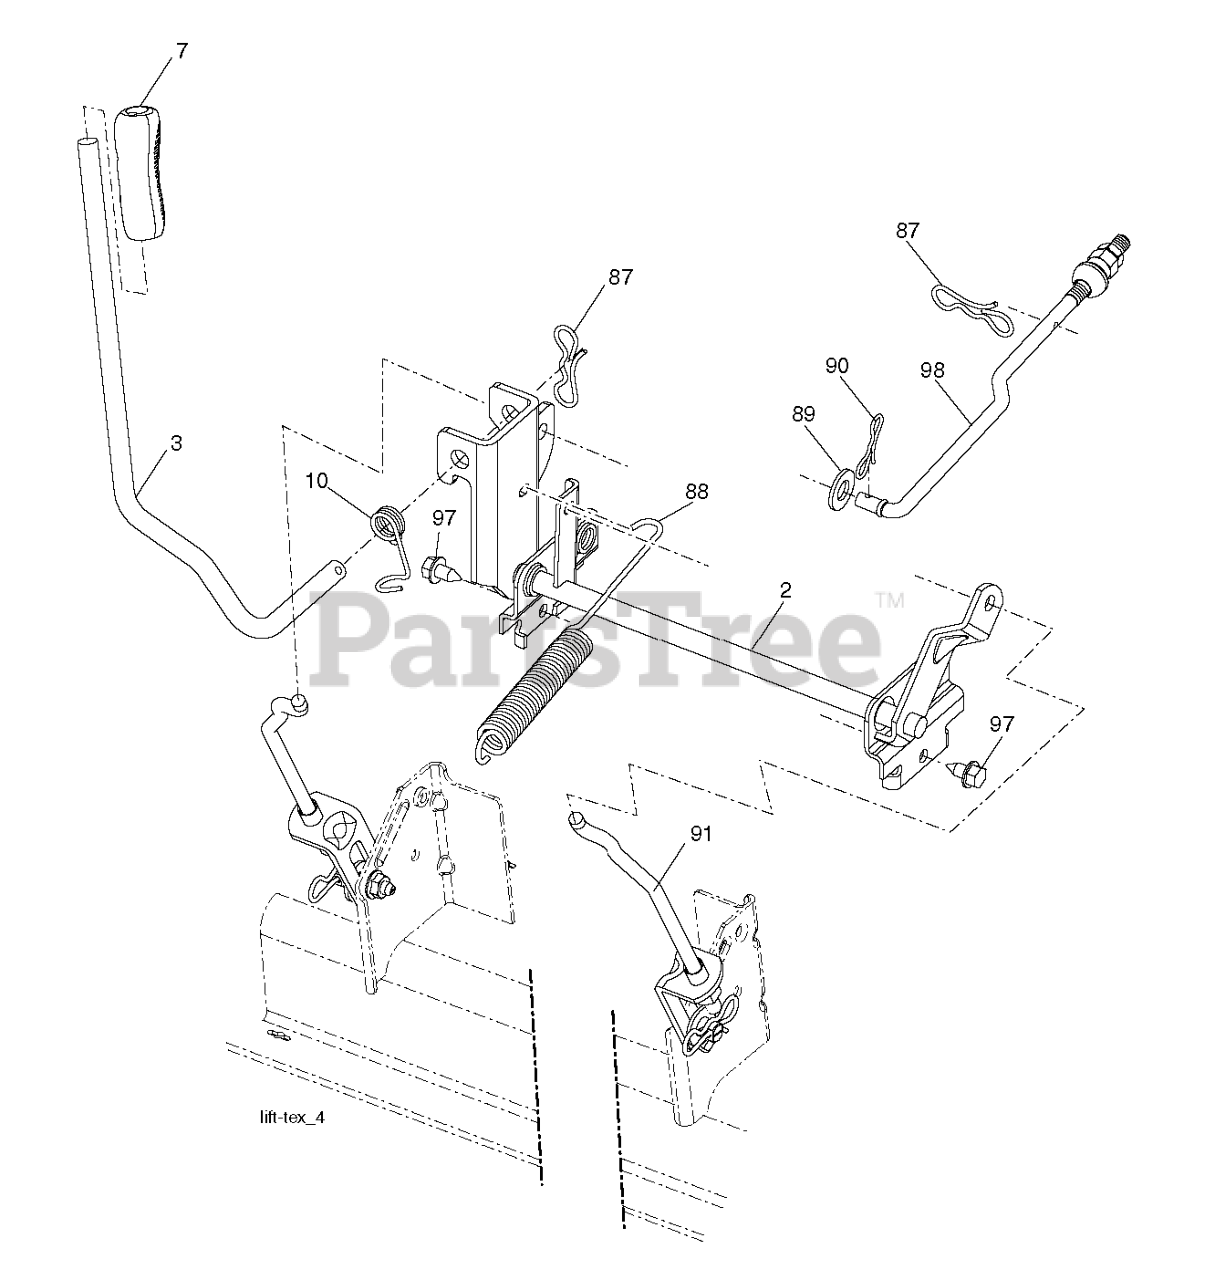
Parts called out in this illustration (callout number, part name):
2	SHAFT.ASM.LIFT.CROSS.H
3	LEVER.LIFT.HANDLE.LT
7	GRIP.LEVER.5625.ID
10	SPRING.TORSION.LIFT.HANDLE
87	PIN.COTTER.7/16.BOW TI.
88	SPRING.LIFT.ASSIST.LT
89	WASHER.CLEAR.ZINC
90	PIN.COTTER.5/16.BOW TI
91	LINK.ASM.LIFT.REAR
97	SCREW 3/8-16X3/4
98	LINK.ASM.SUSP.FRONT.MW
